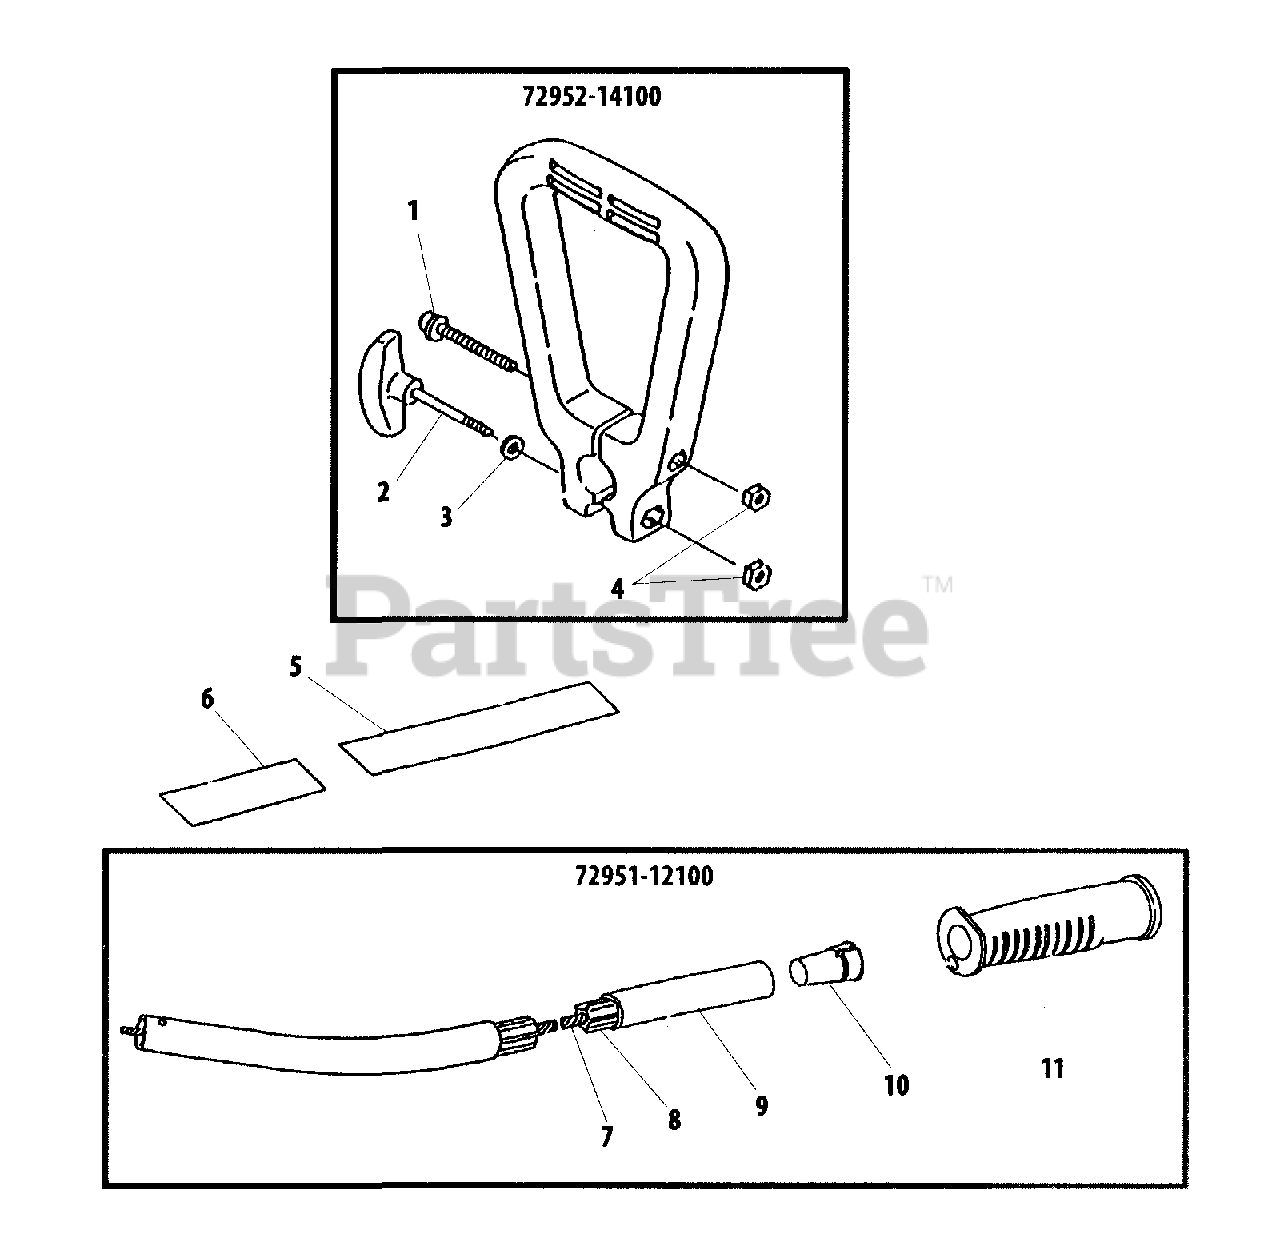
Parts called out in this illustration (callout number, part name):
1	SCREW
2	THUMBSCREW
3	WASHER
4	NUT - 6
5	LABEL - MODEL
6	LABEL - CAUTION
7	DRIVESHAFT - FLEXIBLE
8	LINER - FLEXIBLE
9	MAIN PIPE ASSY
10	GUIDE, SHAFT
11	GRIP - REAR
72951-12100	MAIN PIPE ASSY
72952-14100	HANDLE ASSY
